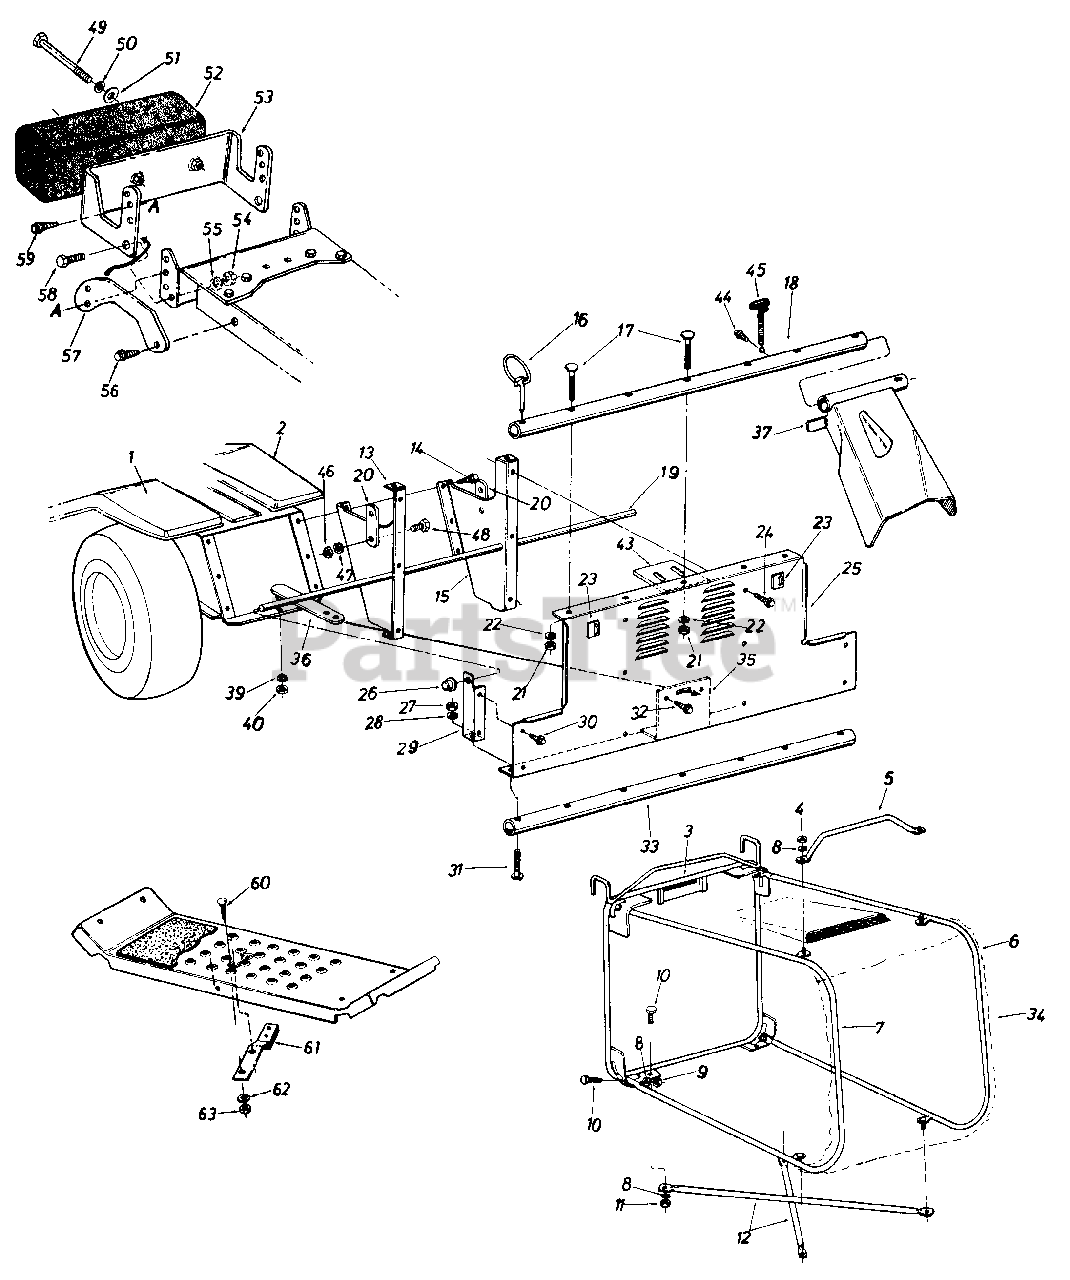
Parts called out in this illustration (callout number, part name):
3	Grass Catcher Frame Ass'y.
4	Hex Cent. L-Nut 1/4-20 Thd.
5	Grass Catcher Handle
9	Hex Cent. L-Nut 1/4-20 Thd.
10	Hex Bolt 1/4-20 x .62" Lg.
11	Hex Cent. L-Nut 1/4-20 Thd.
12	Bottom Cross Brace
13	Grass Catcher Support Brkt. -L.H.
14	Hex Wash. Hd. Self-Tap Scr. 5/16-18 x .75" Lg.
15	Grass Catcher Support Brkt. -R.H.
16	Klick Pin
17	Curved Carr. Bolt 5/16-18 x 1.75" Lg.
18	Grass Catcher Support Tube
19	Tubing .38" I.D. x 39.75" Lg.
20	Fender Support Brkt.
21	Hex Nut 5/16-18 Thd.
22	L-Wash. 5/16" I.D.
23	Safety Switch
24	Hex Wash. Hd. Self-Tap Scr. 1/4-20 x .50" Lg.
25	Grass Catcher Adapter
26	Cap Speed Nut 1/2" Rod
27	Hex Nut 5/16-18 Thd.
28	L-Wash. 5/16" I.D.
29	Chute Extension Support Brkt.-L.H.
30	Hex Wash. Hd. Self-Tap Scr. 1/4-20 x .50" Lg
31	Curved Carr. Bolt 5/16-18 x 1.75" Lg.
32	Hex Wash. Hd. Self-Tap Scr. 1/4-20 x 50" Lg.
33	Tubing 1.00" I.D. x 40.25"
34	Grass Catcher Bag
35	Hitch Bracket
40	Hex Jam Nut 1/2-13 Thd.
43	Grass Catcher Support Plate
44	Hex AB-Tap Scr. 1/4-20 x 62" Lg.
45	Spring Latch Ass'y.
46	Hex Nut 1/4-20 Thd.*
47	L-Wash. 1/4" I.D.*
48	Hex Bolt 1/4-20 x .50" Lg.*
49	Hex Bolt 3/8-16 x 4.50" Lg.
50	Bell-Wash. 400" I.D. x .88" O.D.
51	Fl-Wash. 890" I.D. x 1.12" O.D.
52	Front Counterweight
53	Weight Bracket Ass'y.
54	Hex Jam Nut 7/16" Thd.
55	L-Wash. 7/16" I.D.
56	Hex Wash. AB-Tap Scr. 5/16 x 1.0" Lg.
57	Weight Brkt. Tie Strap
58	Hex Bolt 7/16-20 x 1.0" Lg.
59	Hex Wash. AB-Tap Scr. 5/16 x 1.0" Lg.
60	Carr. Bolt 1/4-20 x .62" Lg.
61	Blade Brake Ass'y.
62	L-Wash. 1/4n I.D.
63	Hex Nut 1/4-20 Thd.
